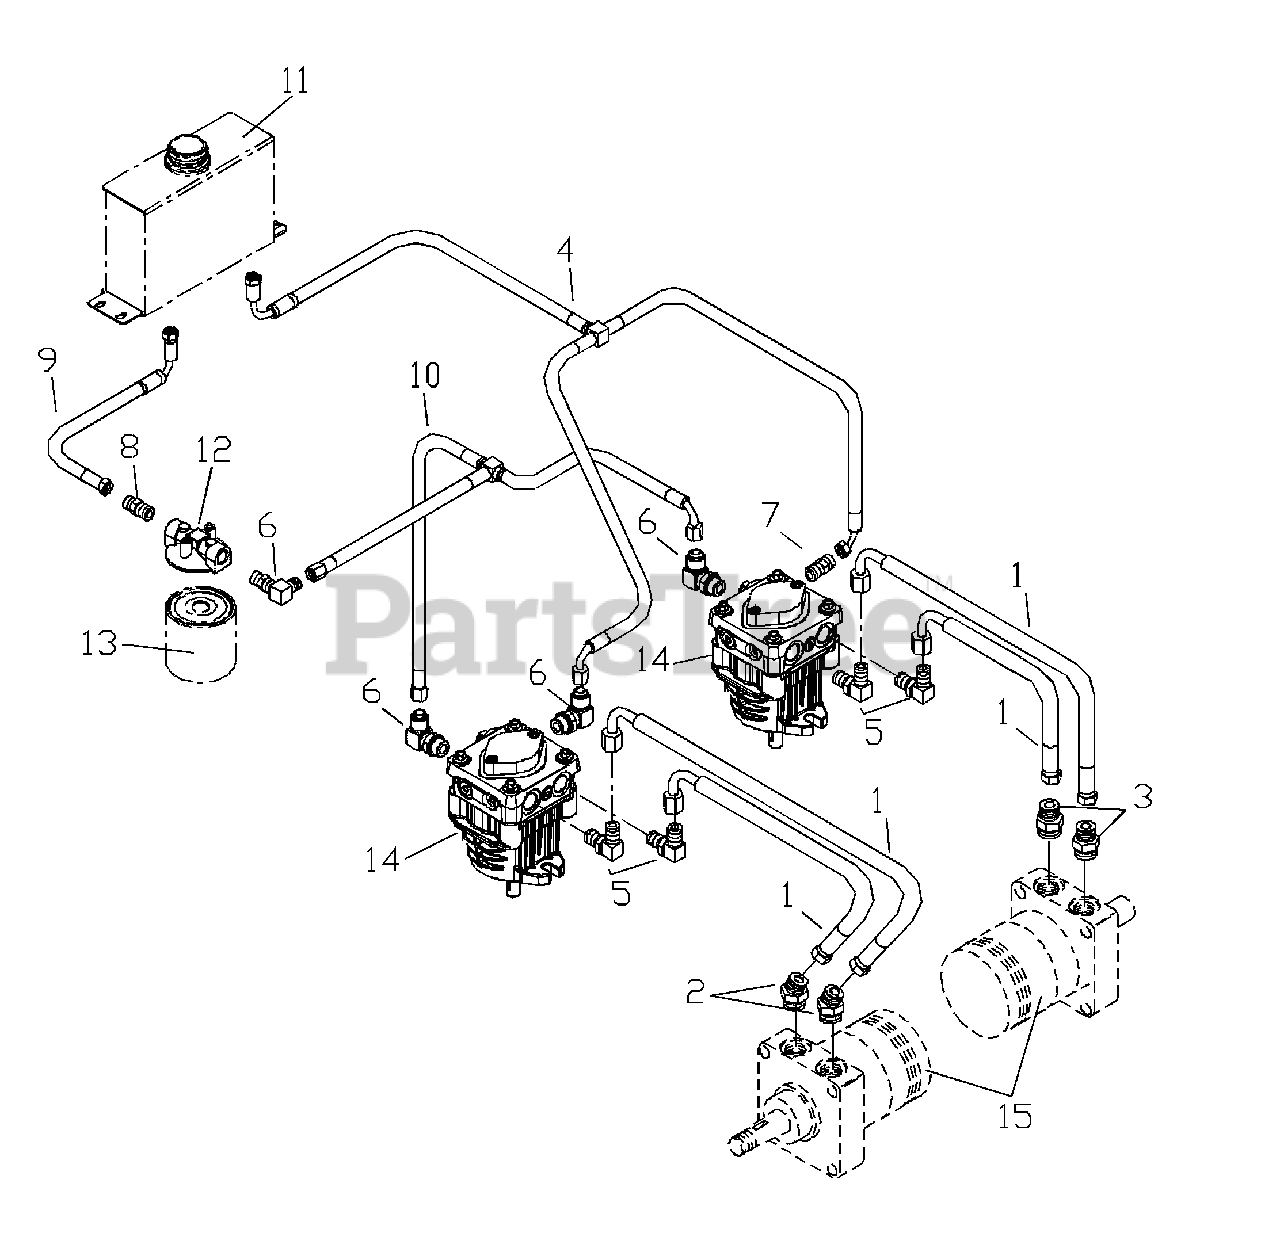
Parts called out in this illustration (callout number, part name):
1	HOSE
2	45 DEGREE ELBOW
3	STRAIGHT CONNECTOR
5	90 DEGREE ELBOW
6	90 DEGREE ELBOW
8	STRAIGHT CONNECTOR
9	HOSE
12	FILTER HEAD
14	PUMP
15	HYD. MOTOR
